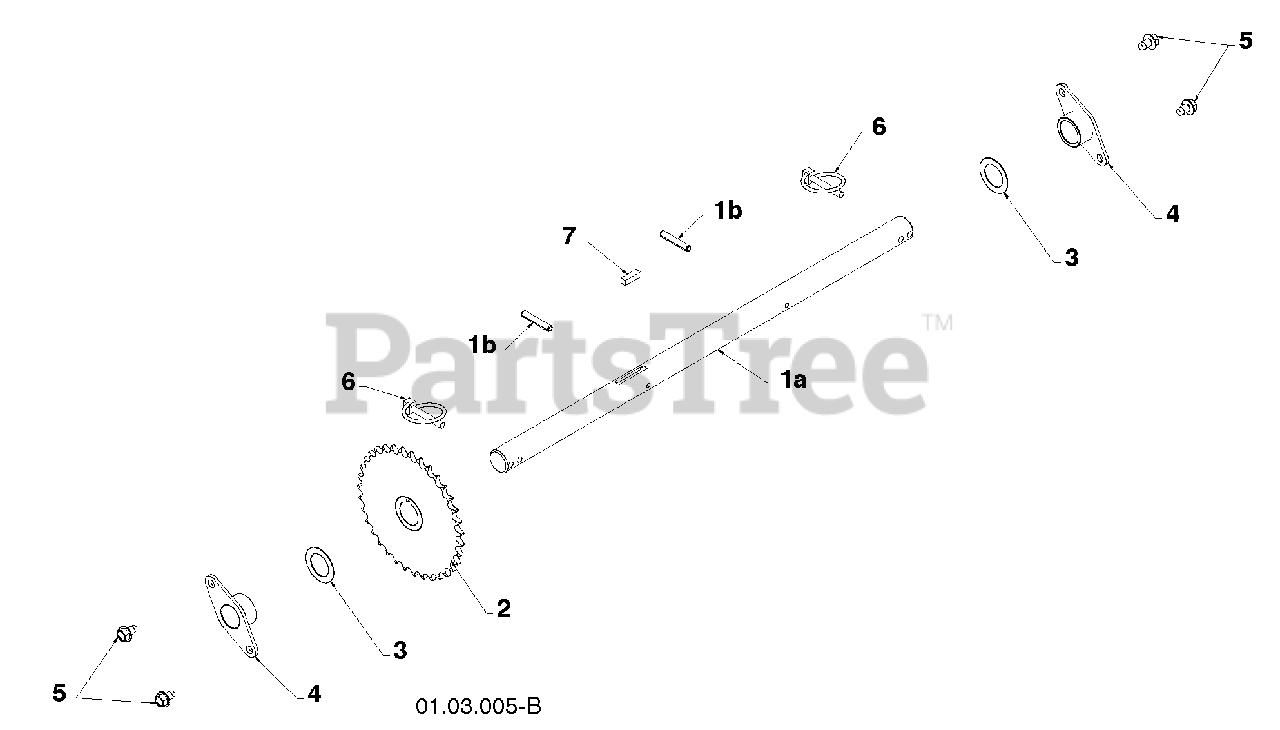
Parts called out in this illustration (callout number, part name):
1	(assy of 1a,1b) AXLE ASSEMBLY
2	SPROCKET
3	THRUST WASHER
4	BEARING
5	BOLT 5/16-18 X .500
6	CLIK PIN
7	SQUARE KEY
